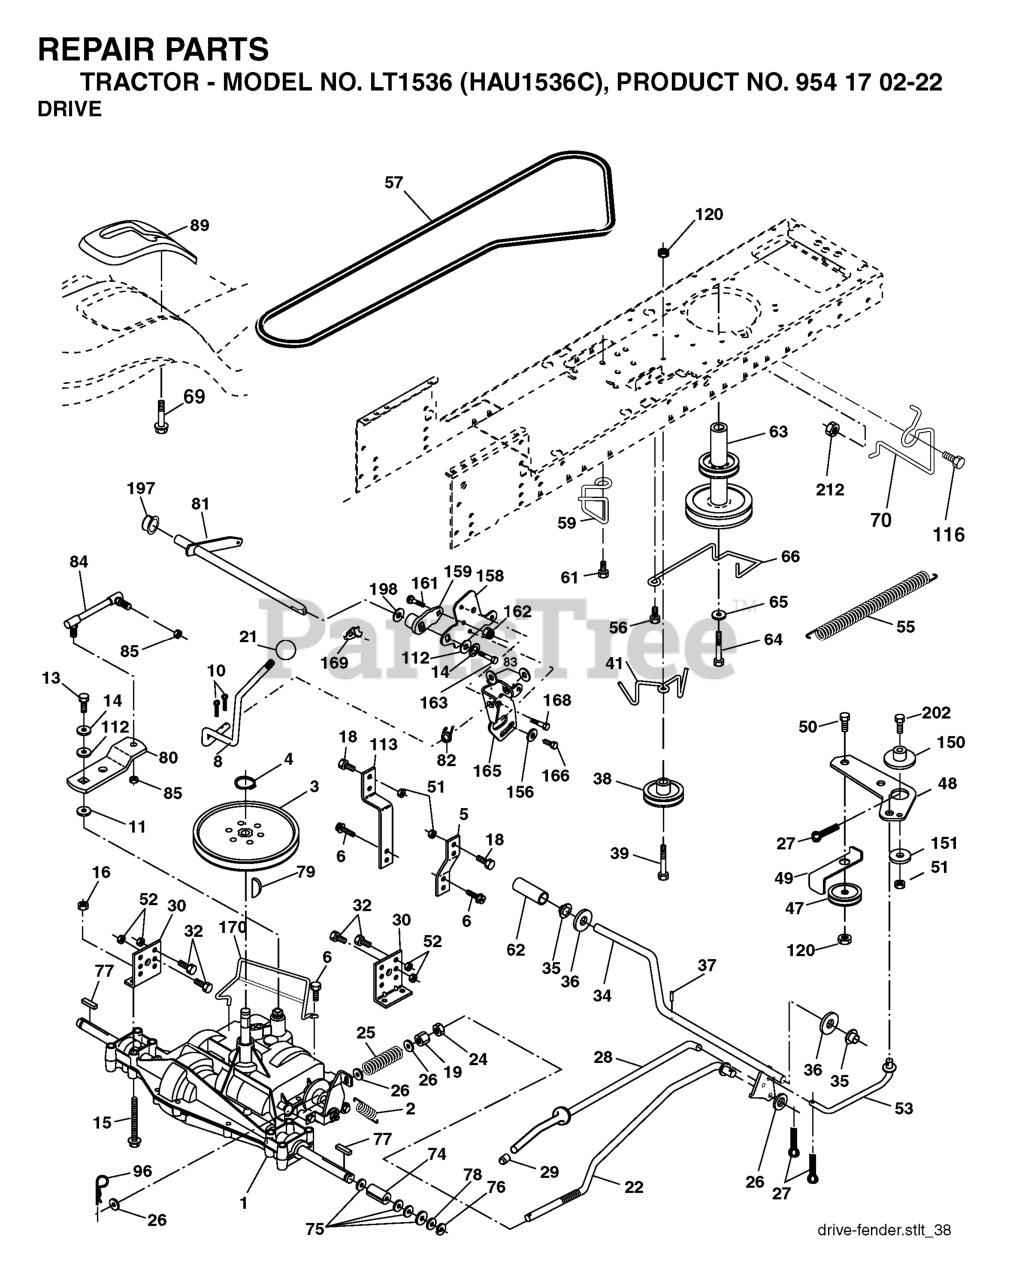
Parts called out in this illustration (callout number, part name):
2	SPRING,BRAKE RETURN
3	PULLEY TRANS
4	RETAINING RING LT
5	STRAP TORQUE
6	SCREW 5/16"
8	ROD.SHIFT.FENDER.ADJ.STLT
10	PIN COTTER
11	WASH-SHFT PLT LT
13	BOLT 1/4-28X3/4
14	LOCKWASHER
15	BOLT HEX 5/16-18 GR 5
16	NUT.71038.31-18.HEX.NYLOCK
19	NUT
21	KNOB.DUCKHEAD.1/2
24	NUT
25	SPRING ROD LT
26	WASHER
27	COTTER PIN
28	ROD, PARKING BRAKE
29	PLUNGER CAP
30	BRKT, MOUNT TRNSAXLE
32	BOLT
34	SHAFT, FOOT PEDAL
35	BEARING.NYLON
37	DRIVE PIN
38	PULLEY IDLER COMPOSITE
41	KEEPER, BELT IDLER
47	IDLER PULLEY
48	BELLCRANK, CLUTCH
49	RETAIN BELT
50	BOLT.3/8-16X1.50
52	LOCKNUT
53	LINK, CLUTCH LT
55	SPRING, RETURN LT
56	SCREW.3/8-16
57	V-BELT
59	KEEPER, BELT CENTER
61	SCREW 3/8-16X.875
62	PEDAL COVER T
63	ENGINE PULLEY
64	BOLT HEX 7/16-20X4-1/4"
65	LOCKWASHER
66	KEEPER BELT ENGINE
69	SCREW.HI-LO.CONSOLE
70	KEEPER BELT ENG
74	SPACER AXLE
77	SQUARE KEY
79	KEY STD (1373) DANA
81	SHAFT ASM CROSS TAPERED
82	SHIFT SPRING
83	WASHER
84	LINK.TRNSAXLE
85	NUT LOCK CENTER 1/4 -28 FNTHD
89	CONSOLE.SHIFT.STLT.6SP
96	RETAINER M
113	STRAP TORQUE LH LT
116	BOLT D
120	NUT LOCK FLG 3/8-16 UNC
150	SPACER, RETAINER
151	WASHER 12/32X2X10GA
156	WASHER.SRRTD.5/16
158	BRACKET
159	RB HUB.SHIFT
161	BOLT
162	NUT.CROWNLOCK.1/4
165	RP BRACKET
166	CAPSCREW.HXHD.FLG.5/16-18X.625
168	BOLT.SHOULDER.5/16-18X
169	PLATE.FASTENING.CROSS.SHAFT
170	KEEPER BELT T/A
197	NYLINER SNAP 5/8" ID
198	WASHER.NYL.7/8IDX.105"HYD CR
212	NUT
